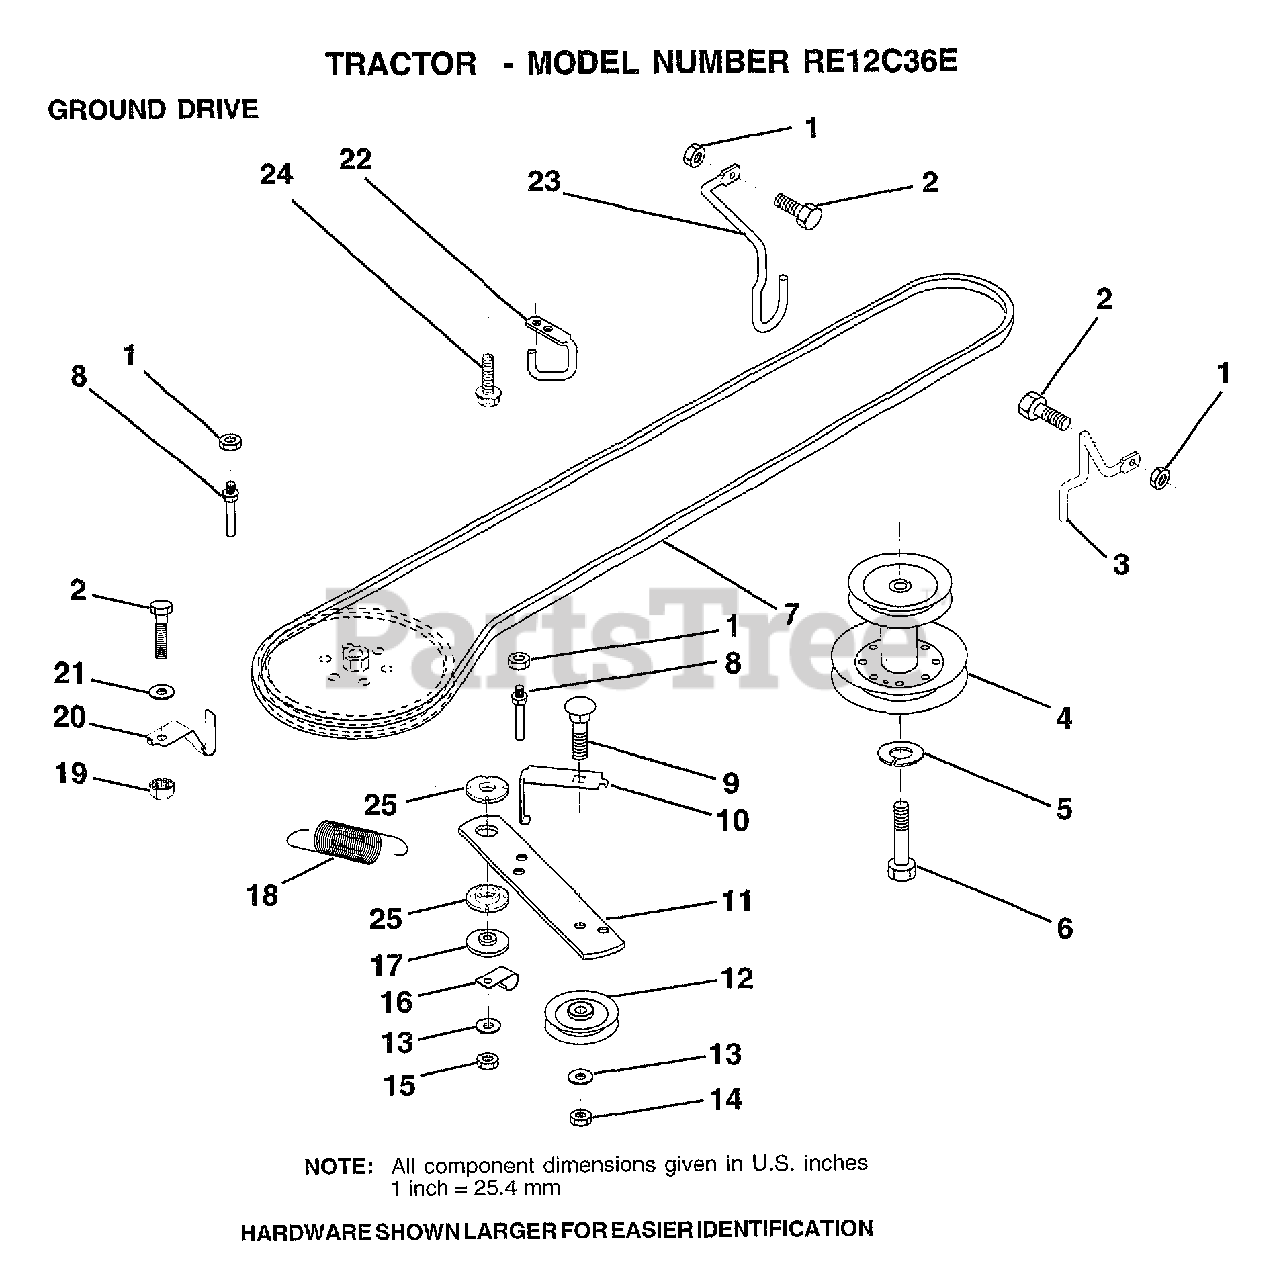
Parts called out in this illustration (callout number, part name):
2	BOLT
3	KEEPER RH
4	PULLEY.ENGINE.LR
5	LOCKWASHER
6	HEX BOLT
7	V BELT
8	"KEEPER,DRIVE BELT"
9	BOLT
10	"KEEP,IDLER DR BEL"
11	ARM-IDLER.DR.GRND
12	PULLEY.IDLER.FLAT
13	WASHER
14	LOCKNUT
16	"CLIP,INSULATOR"
17	SPACER
20	KEEPER.BELT.T/A
21	WASHER
22	"KEEPER,FRA DR BEL"
23	KEEPER MOWER LH
24	SCREW
25	BUSHING.NYLON
